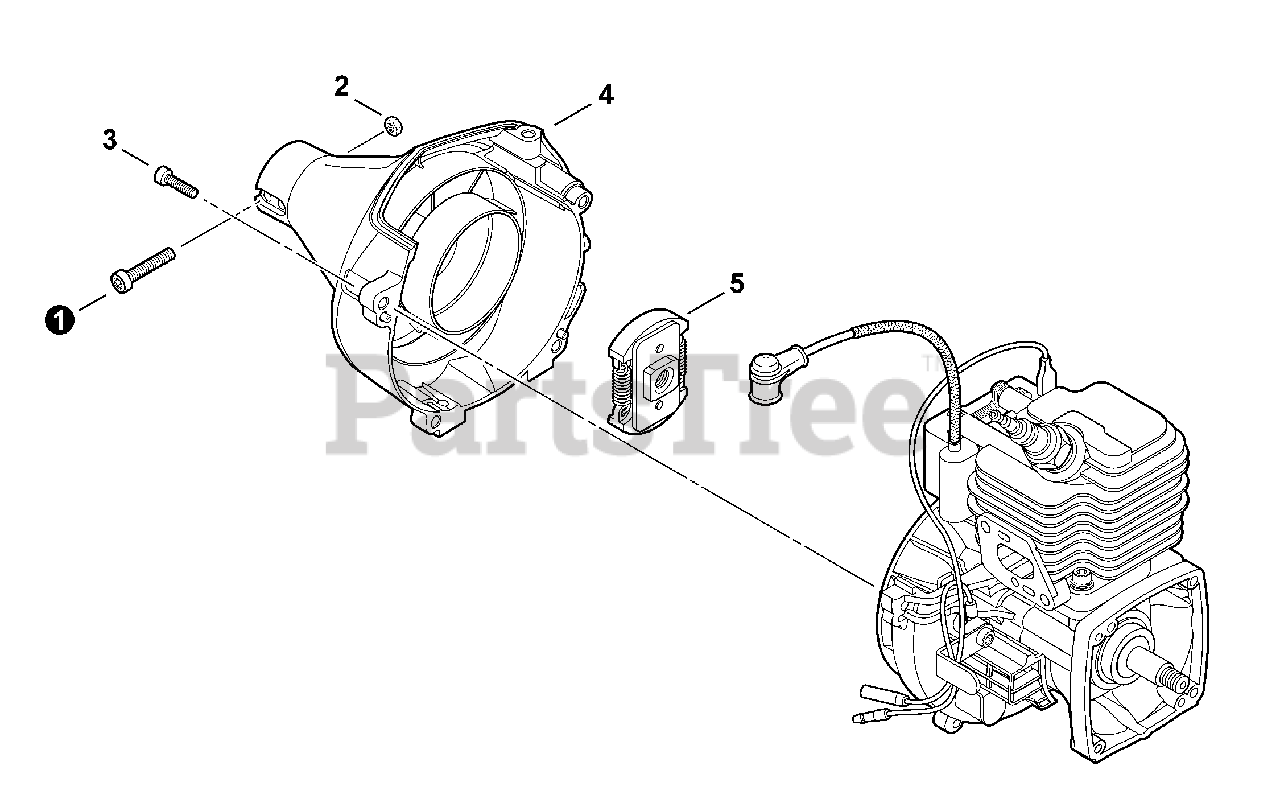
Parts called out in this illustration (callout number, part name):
1	SCREW - 5×25
3	SCREW - 4×16 -- TORX
4	FAN CASE ASY
5	CLUTCH ASY
